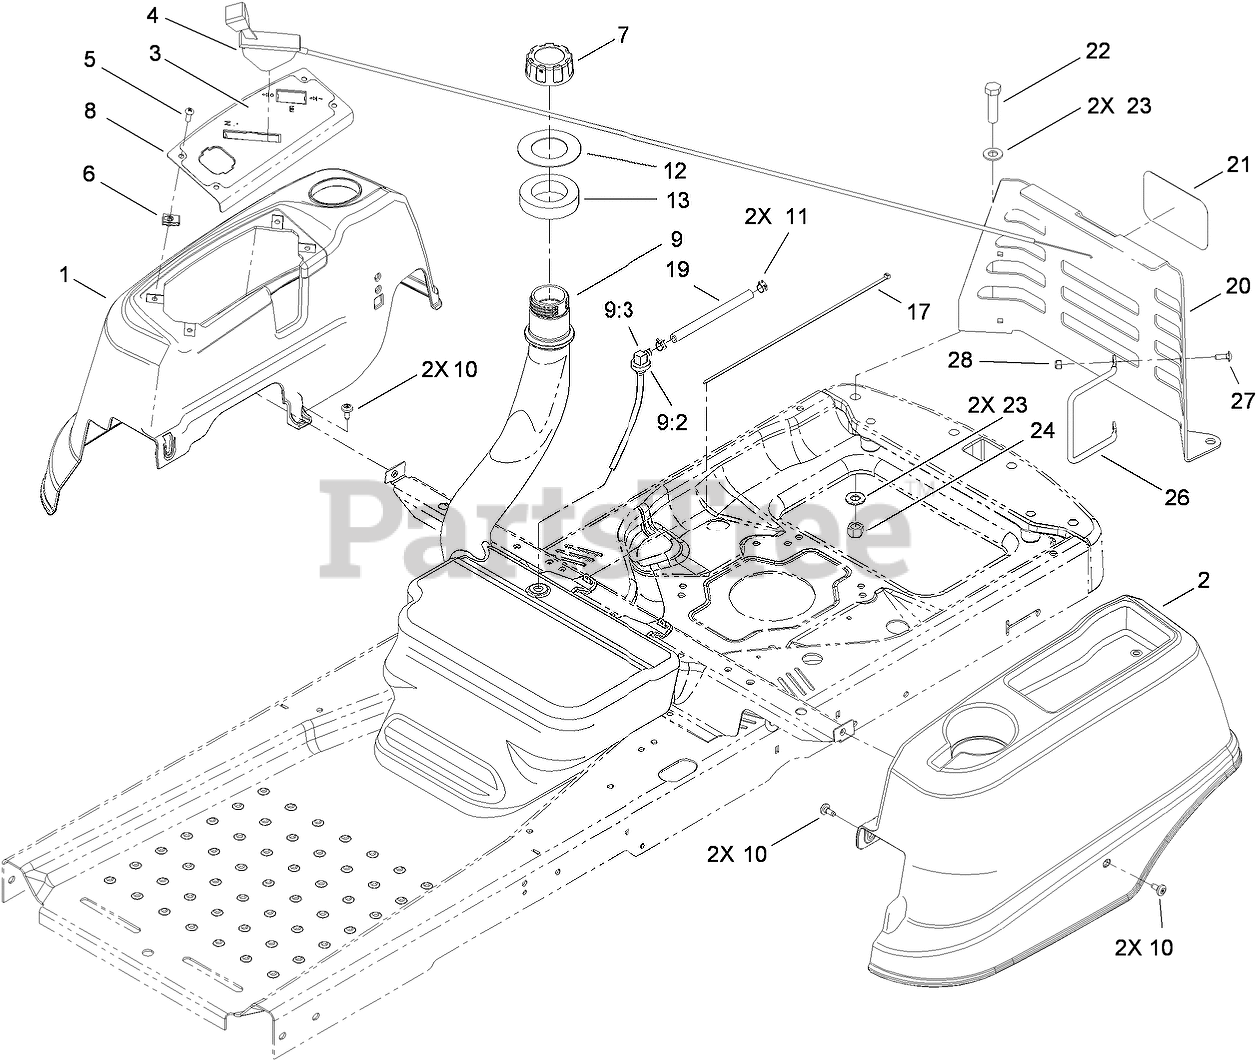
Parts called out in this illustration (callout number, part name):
1	POD-RH
2	POD-LH
3	DECAL-PANEL, CONTROL
4	CABLE-THROTTLE
5	SCREW-PRH
7	CAP-GAS
8	PANEL-CONTROL
9	FUEL TANK ASM
9:2	BUSHING
9:3	FITTING-90 DEGREE
10	SCREW-SHOULDER
11	CLAMP-HOSE
12	WASHER-RUBBER
13	SEAL-FOAM
17	TIE-CABLE
19	HOSE-FUEL
20	SUPPORT-COVER, REAR
22	SCREW-HH
23	WASHER-FLAT
24	NUT-LOCK, NI
26	GUARD-MUFFLER
27	BOLT-CARR
28	NUT-LOCK, NI
